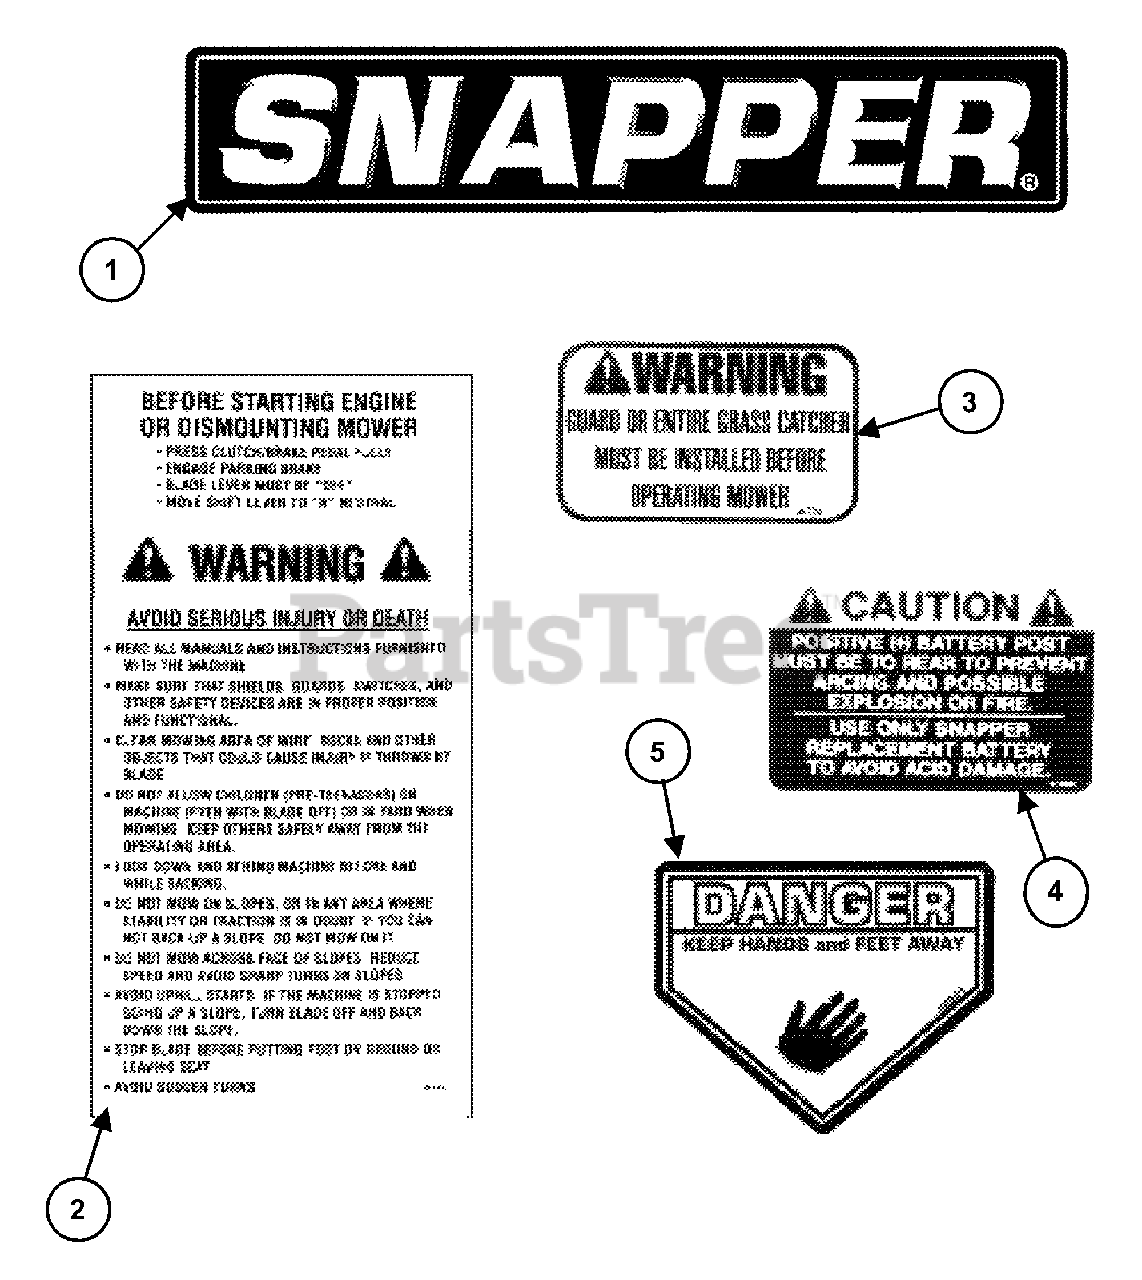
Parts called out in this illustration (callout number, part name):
1	DECAL, SNAPPER
2	DECAL, Warning, Safety Instruction
3	DECAL, Chute/Deflector
4	DECAL, Caution, Battery
5	DECAL, Danger (Heavy Adhesive)
